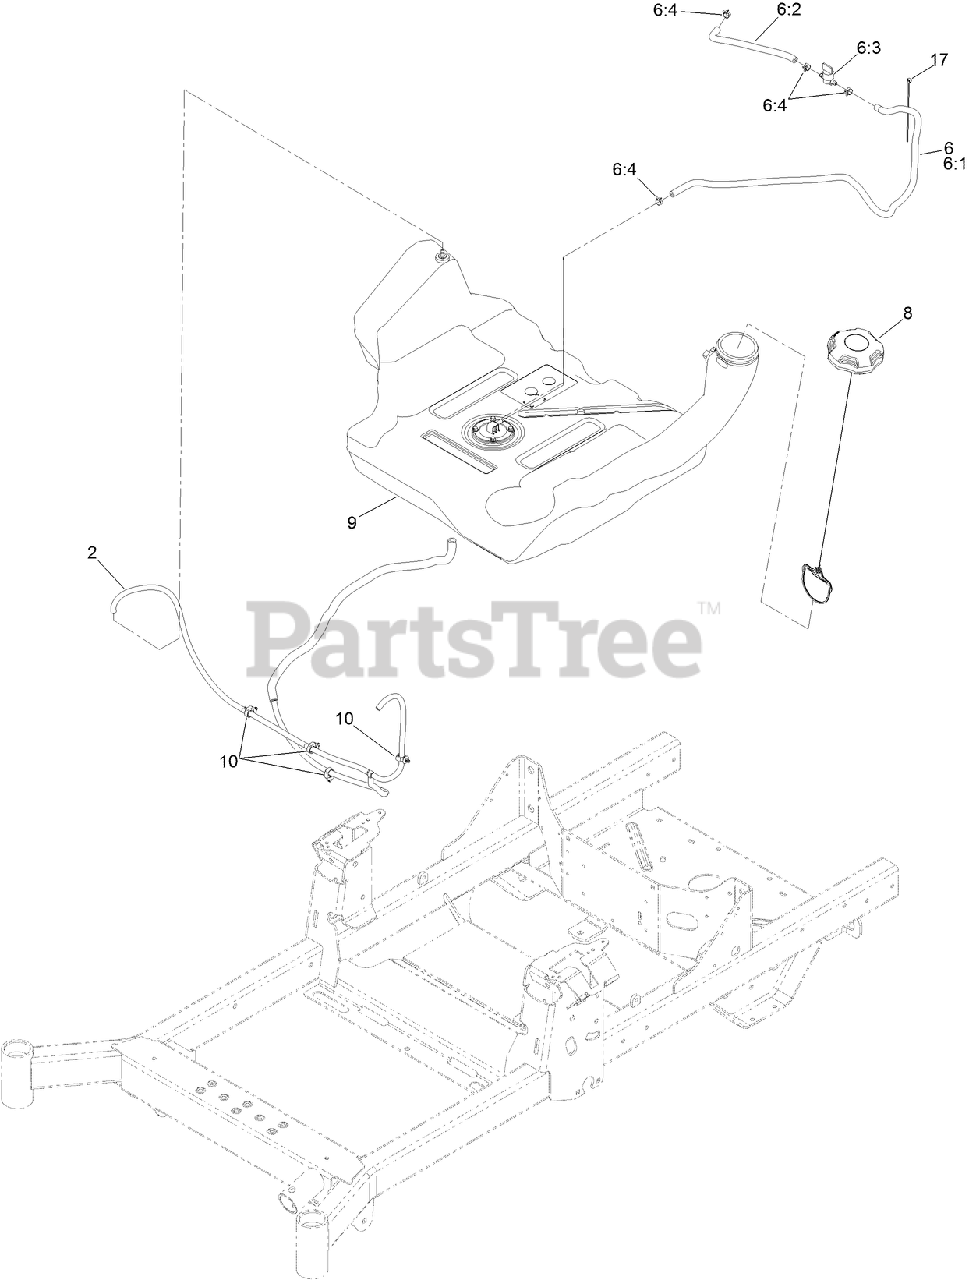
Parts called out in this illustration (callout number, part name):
2	HOSE-VENT
6	FUEL HOSE ASM
6:1	HOSE-FUEL
6:2	HOSE-FUEL
6:3	VALVE-FUEL
6:4	CLAMP-HOSE
8	CAP-FUEL
9	TANK-FUEL
17	TIE-CABLE
